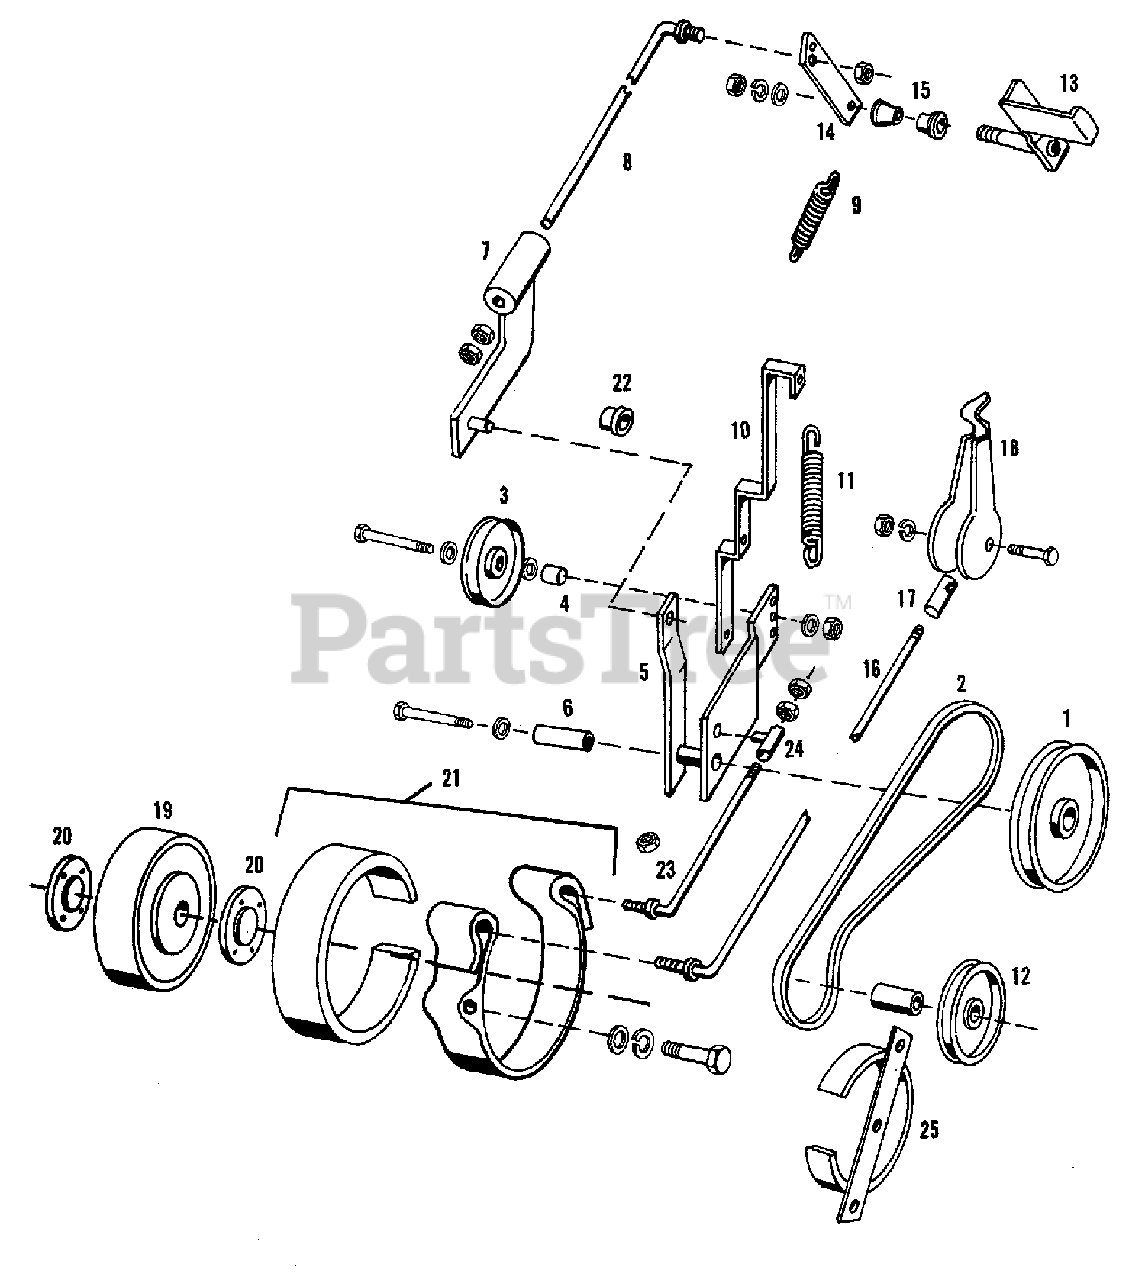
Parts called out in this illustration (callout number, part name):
2	BELT, Hydrostatic Drive
3	PULLEY, Idler
3	WASHER, 3/8
4	CAPSCREW, 3/8NC x 2-1/4
4	LOCKWASHER, 3/8
4	NUT, 3/8NC
4	NUT, 3/8NC-Lock
5	LEVER ASSEMBLY, Idler
5	WASHER, .781 x 1.25 x 7 Ga
5	NUT, 3/4NF-Jam Lock
6	WASHER, 7/16
6	CAPSCREW, 7/16NC x 3-3/4 Gr8
6	LOCKWASHER, 7/16
7	GUIDE ASSEMBLY, Rod
7	NUT, 7/16NC
7	NUT, 5/16NC-Lock
8	ROD, Clutch & Brake
8	NUT, 5/16NC
10	BRACKET, Spring
11	SPRING, Extension
12	PULLEY, Driven
12	SCREW, 3/8NC x 3/4 "Taptite"
12	SETSCREW, 5/16NC x 5/16
13	PEDAL ASSEMBLY, Foot
14	ARM, Foot Pedal
14	WASHER, 3/8
14	LOCKWASHER, 3/8
14	NUT, 3/8NC
15	BUSHING, Flanged
16	ROD, Parking Brake
16	NUT, 5/16NC-Lock
16	NUT, 5/16NC
18	LEVER, Parking Brake
18	CAPSCREW, 1/4NC x 1-1/4 Gr8
18	NUT, 1/4NC-Lock
19	DRUM, Brake
20	WASHER, Special
20	WASHER, 7/16
20	NUT, 7/16NC-Lock
21	BAND ASSEMBLY, Brake (Includes LINING)
21	WASHER
21	LOCKWASHER
21	CAPSCREW, 3/8NC x 1-3/4
21	WASHER, .531 x 1.25 x 16 Ga.
22	BEARING, Flanged
23	ROD ASSEMBLY, Brake
23	NUT, 3/8NC
23	NUT, 3/8NC-Lock
24	GUIDE ASSEMBLY, Rod
24	NUT, 5/16NC-Lock
25	RETAINER ASSEMBLY, Belt
